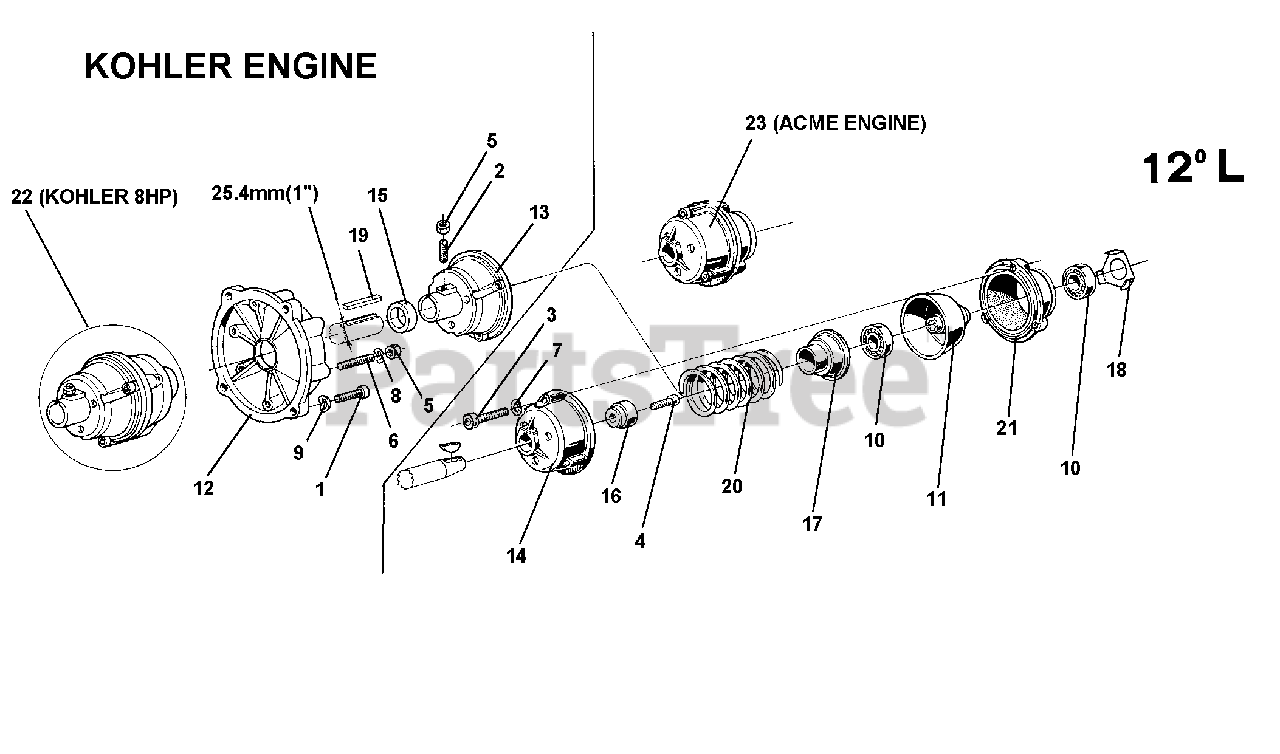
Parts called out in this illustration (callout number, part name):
1	SCREW 3/8 X 1
2	SCREW M8 X 20
3	SCREW TCCEI M6 X 30 UNI 5931
4	SCREW TC CE M8 X 25
6	STUD M8 X 40 X 14 X 14
7	WASHER, LOCK 6.4
8	WASHER, LOCK 8.4
9	WASHER, LOCK 10.5
10	BRNG SKF 17 X 40 X 12 6203 ST
11	LONG CLUTCH CONE
12	BRIGGS STR/KOHLER FLANGE
13	CLUTCH BELL
14	LONG CLUTCH BELL
17	BUSH, SPRING HOLDER
18	BEARING PLATE
20	SPRING CLUTCH
21	LONG CLUTCH RING
23	FITTED LONG CLUTCH
